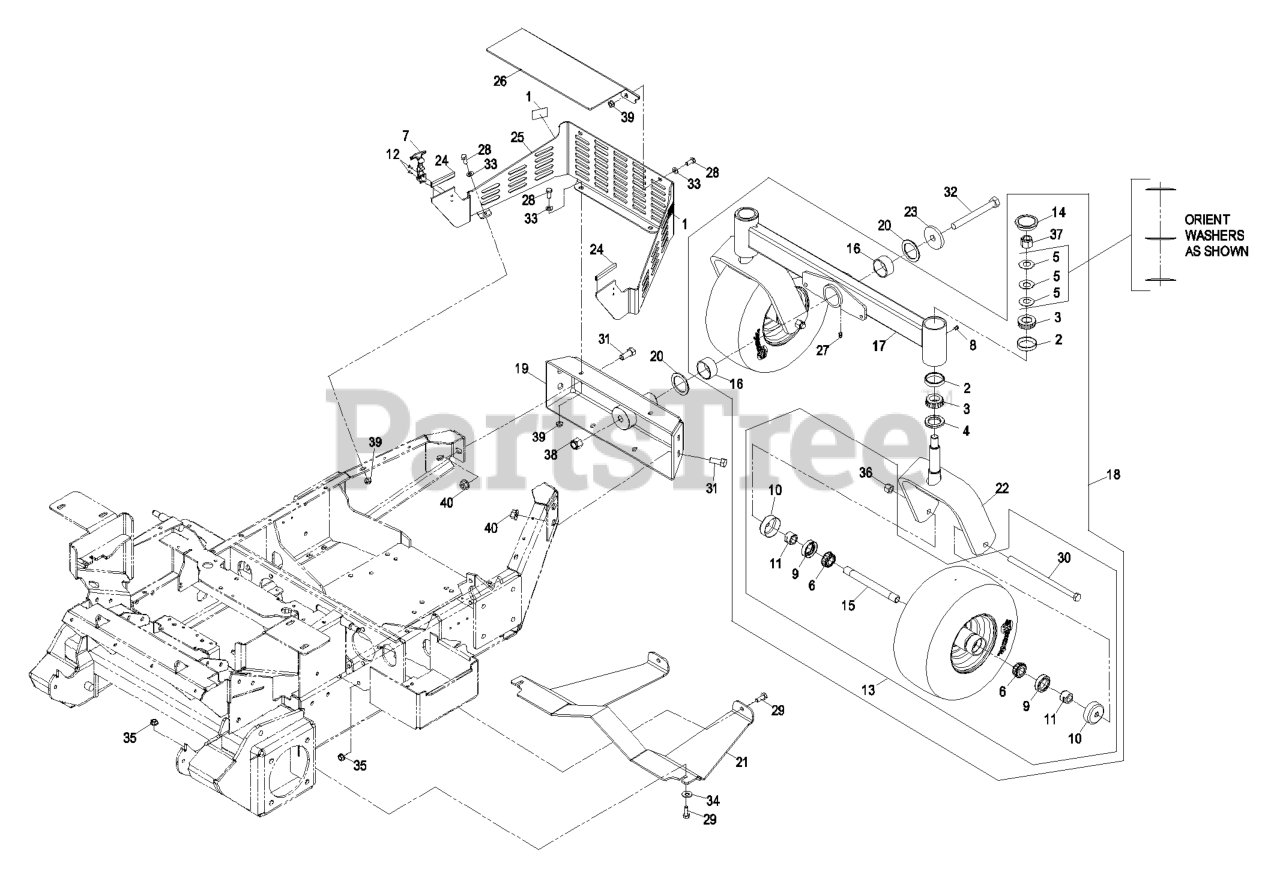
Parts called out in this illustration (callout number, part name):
2	CUP-BEARING
3	Cone-Bearing Tapered Roller
4	SEAL-GREASE
5	WASHER-BELLVILLE
6	BEARING-CONE, TAPERED ROLLER
7	LATCH-RUBBER
9	SEAL-CASTER
10	GUARD-SEAL
11	SPACER-NUT
13	WHEEL & TIRE ASM
14	CAP-GREASE
16	BEARING,1.75"ID X 2"OD
18	Asm, Dual Rear Wheels
20	BEARING,THRUST
23	WASHER (PLATED)
24	STRIP-SEAL
25	ASM,FMZ REAR GUARD
26	COVER,MUFFLER FMZ
27	FITTING-GREASE
28	SCREW-HH
29	SCREW-HH
30	SCREW-HH
31	SCREW-HH
32	SCREW-HH
33	WASHER-PLAIN
34	WASHER-FLAT
35	NUT-HHF, WHIZ
36	NUT-LOCK, NI
37	NUT-LOCK, NI
38	NUT-LOCK, NI
40	NUT-HHF
